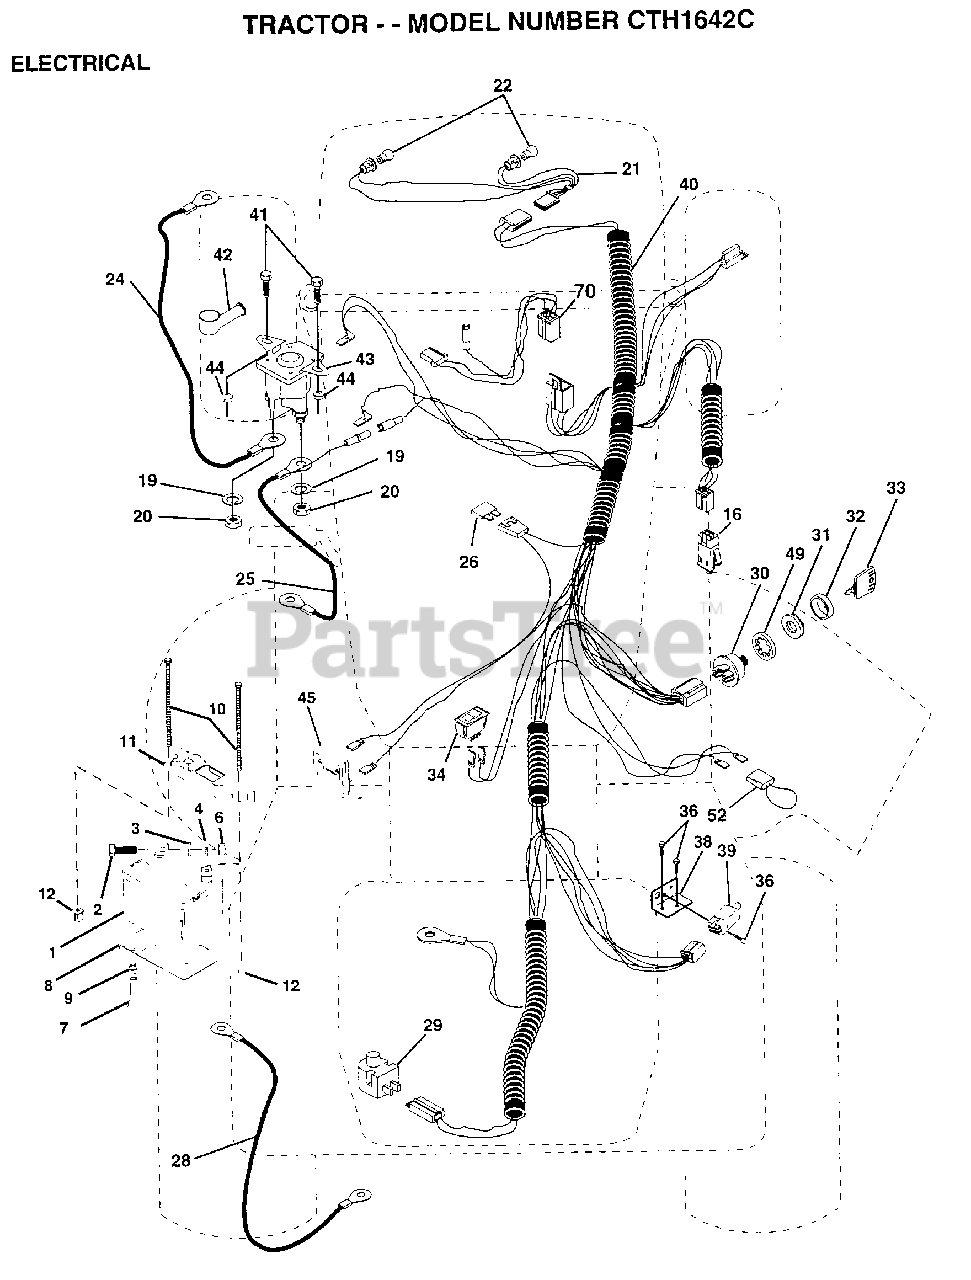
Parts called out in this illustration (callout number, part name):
2	BOLT LT
3	WASHER
4	LOCKWASHER
7	"DRAIN TU T, BATT"
8	"TRAY T, BATTERY"
9	HOSE CLAMP T
16	SWITCH INTERLOCK
20	NUT
21	"HARNESS,LIGHT SOC"
22	HEADLAMP BULB
24	"CABLE T, BATTERY"
25	CABLE.6GA.22W/16W
26	FUSE HYT
28	CABLE.GRND.6GA.21
29	SWITCH SEAT
32	COVER KEY SWITCH
33	KEY MLD GEN DELTA
34	SWITCH LT
36	SCREW
38	BRACKET SWITCH IN
39	SWITCH INTERLOCKT
40	HARNESS.IGN.MECH.
41	BOLT HXHD FIN
44	NUT HXKEP 1/4X20
49	WASHER PINNED
52	PROTECTION LOOP
55	SCREW LT
70	HARNESS ENG DUAL
